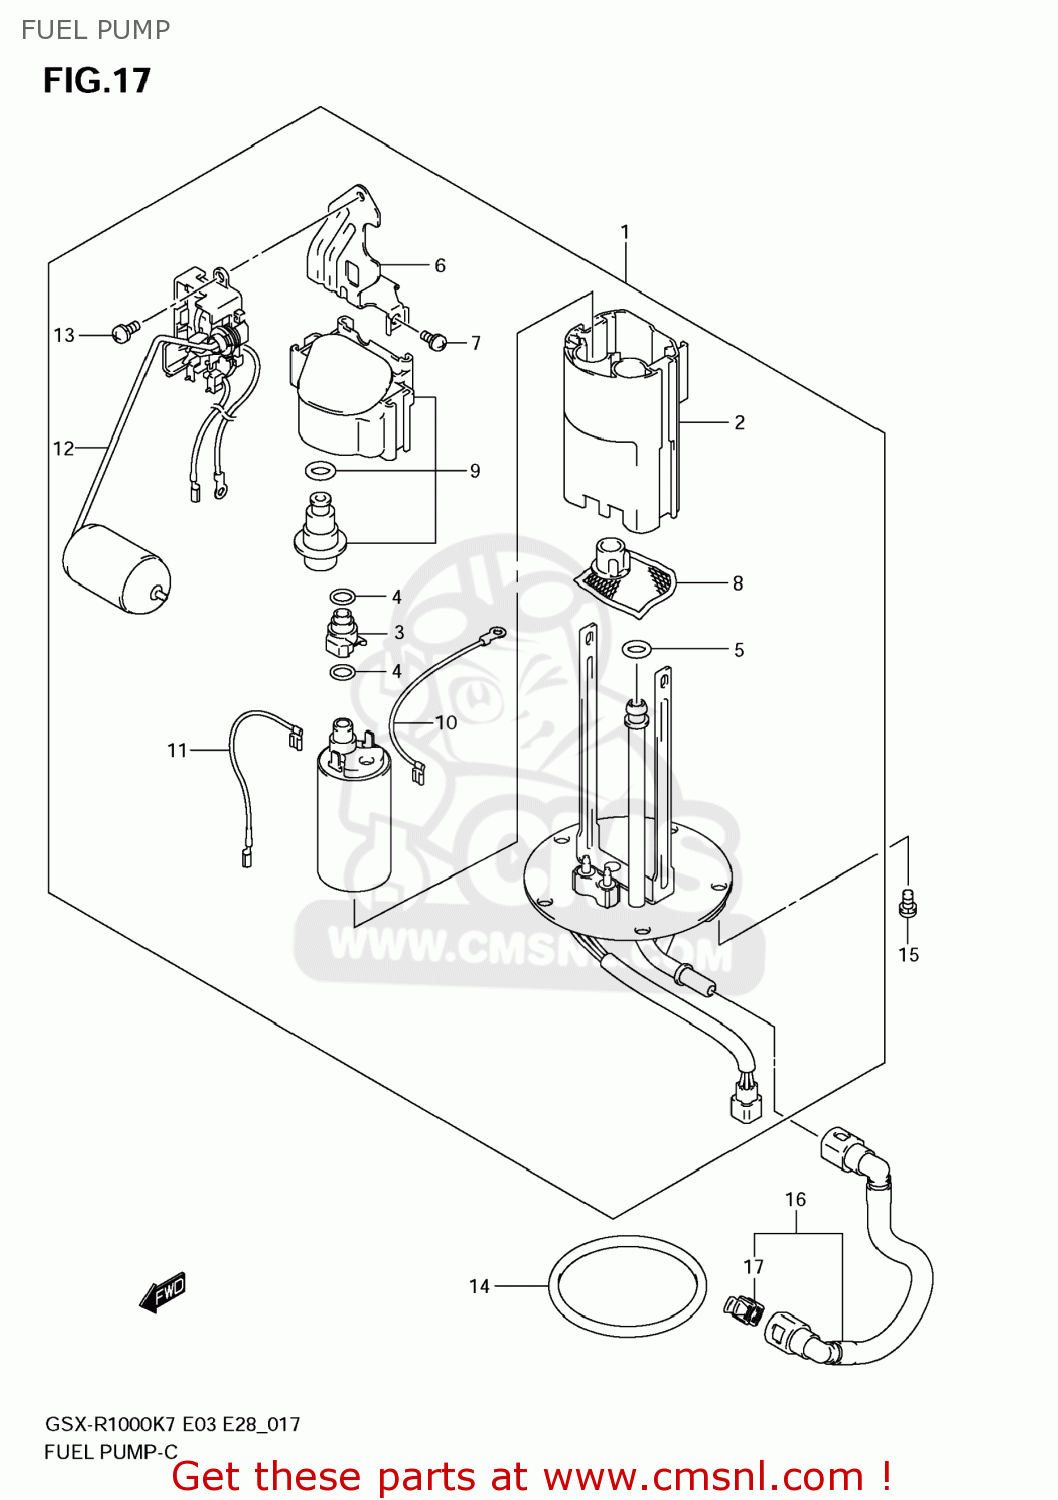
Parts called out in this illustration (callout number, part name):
1	PUMP ASSY,FUEL
2	CUP
3	JOINT
4	O RING
5	O RING
6	BRACKET,GAUGE
7	SCREW
8	STRAINER
9	REGULATOR
10	WIRE,EARTH
11	WIRE,LEAD
12	GAUGE ASSY,FUEL LEVEL SENDER
13	SCREW
14	O RING,FUEL PUMP
15	BOLT
16	HOSE COMP,FUEL
17	RETAINER
